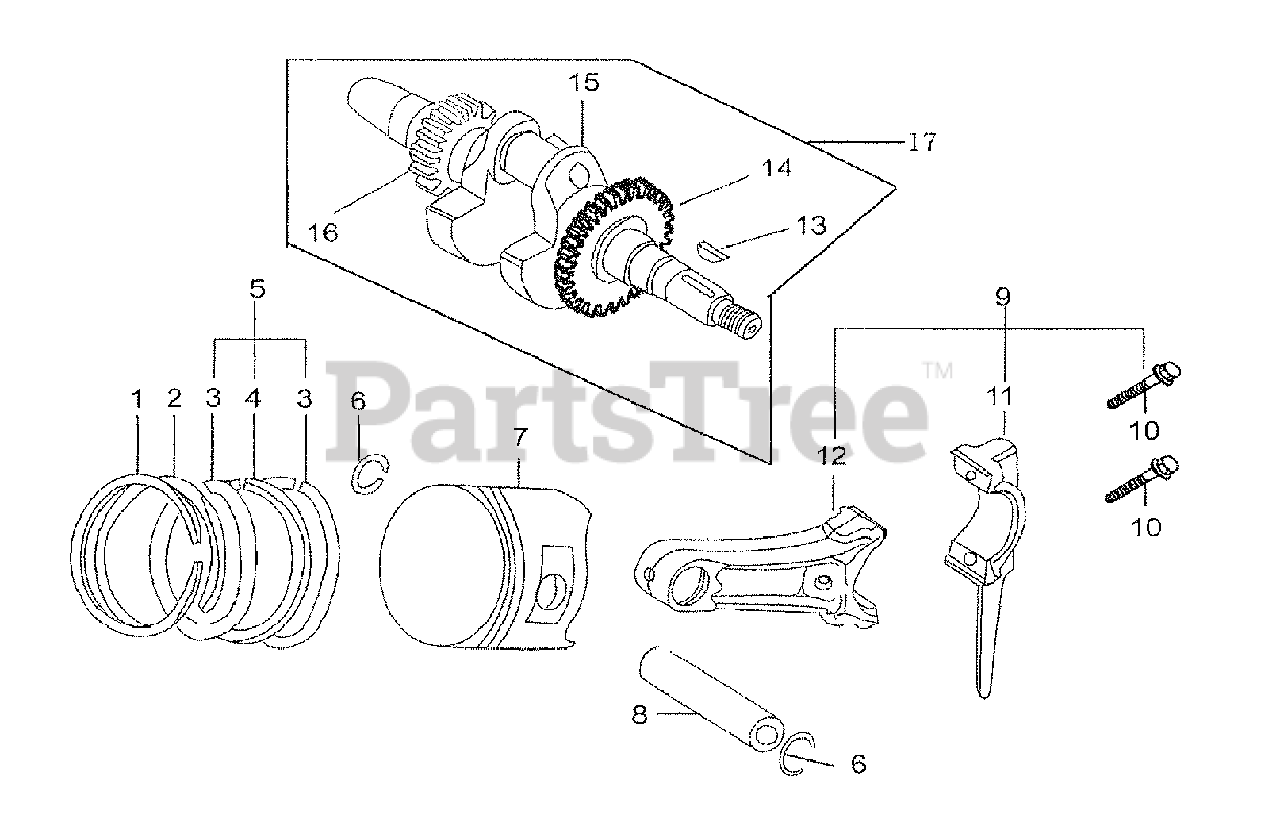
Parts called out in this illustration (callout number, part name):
1	PISTON RING ( I )
2	PISTON RING ( II )
3	SIDE RING
4	WAVE RING
5	RING SET, PISTON (STD)
6	CLIP, PISTON PIN
8	PIN, PISTON
9	CONNECTING ROD ASSY INCLD (10,11,12)
10	BOLT, CONN. ROD 8X32
11	CONNECTING ROD
12	END CAP, CONN. ROD
13	WOODRUFF KEY 5X5X33
14	DRIVE GEAR
15	CRANK SHAFT
16	TIMING DRIVING GEAR
17	CRANK SHAFT,COMP. INCLD (13,14,15,16)
